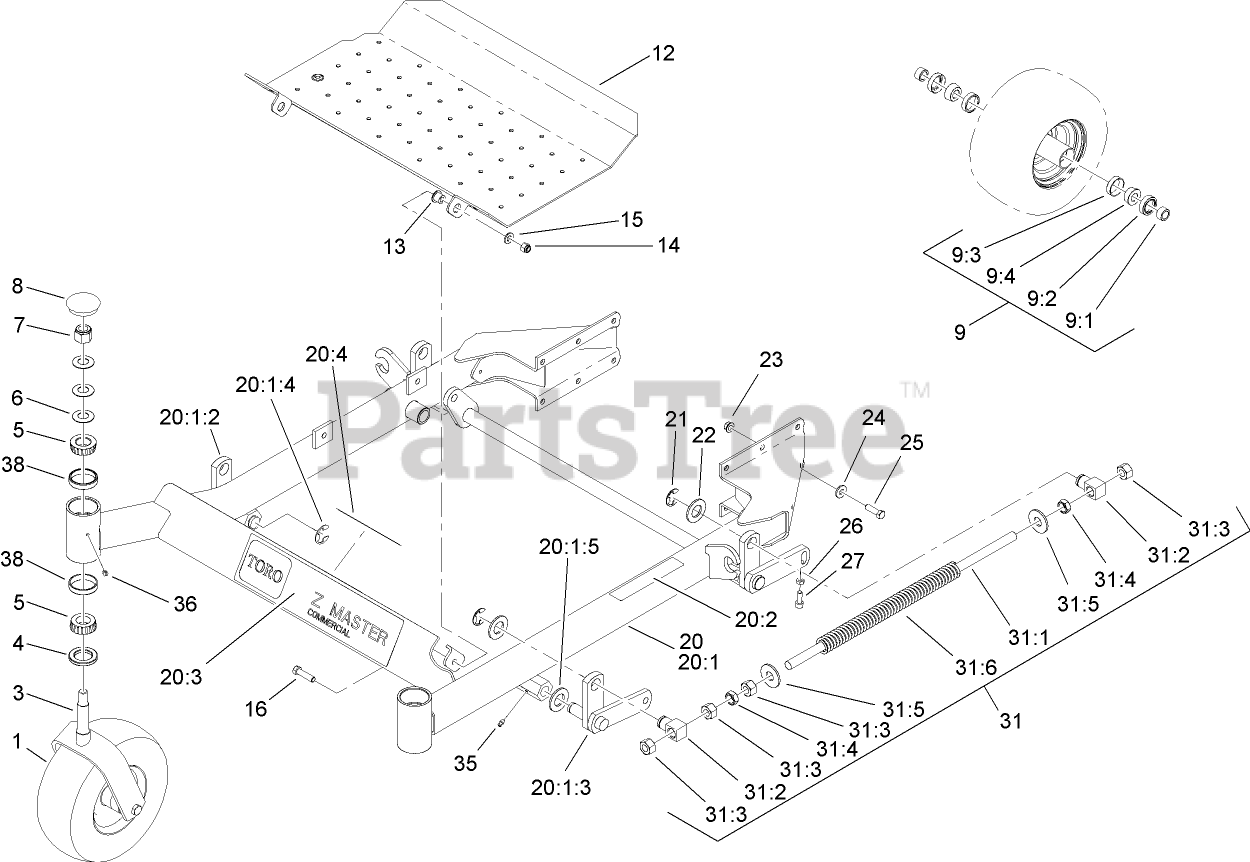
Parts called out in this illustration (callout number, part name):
1	SEMI PNUEMATIC WHEEL ASM
3	CASTER
4	SEAL-GREASE
5	BEARING-CONE, TAPERED
6	WASHER-BELLVILLE
7	NUT-LOCK, NI
8	CAP-GREASE
9	CASTER WHEEL BEARING KIT
9:1	SPACER-BEARING
9:2	SEAL-BEARING
9:3	BEARING-CUP
9:4	BEARING-CONE, TAPER
12	FLOOR PAN
13	BUSHING-FLANGE
14	NUT-LOCK, NI
15	WASHER-FLAT
16	SCREW-HH
20	FRONT FRAME ASM
20:1	FRAME-FRONT
20:1:2	RH LIFT ARM ASM
20:1:3	LH LIFT ARM ASM
20:1:4	RING-RETAINING, EXT
20:1:5	WASHER-FLAT
20:2	DECAL-WARNING
20:4	DECAL-WARNING
21	RING-RETAINING, EXT
22	WASHER-FLAT
23	NUT-HHF, WHIZ
24	WASHER-BELLEVILLE
25	SCREW-HH
26	NUT-JAM
27	SCREW-HSH
31	FRONT FRAME SPRING ASM
31:1	ROD-LIFT, DECK
31:2	SWIVEL-DECK MOUNT, REAR
31:3	NUT-HEX
31:4	NUT-JAM
31:5	WASHER-FLAT
31:6	SPRING-SUPPORT, DECK
35	FITTING-GREASE
38	BEARING-CUP, TAPERED
